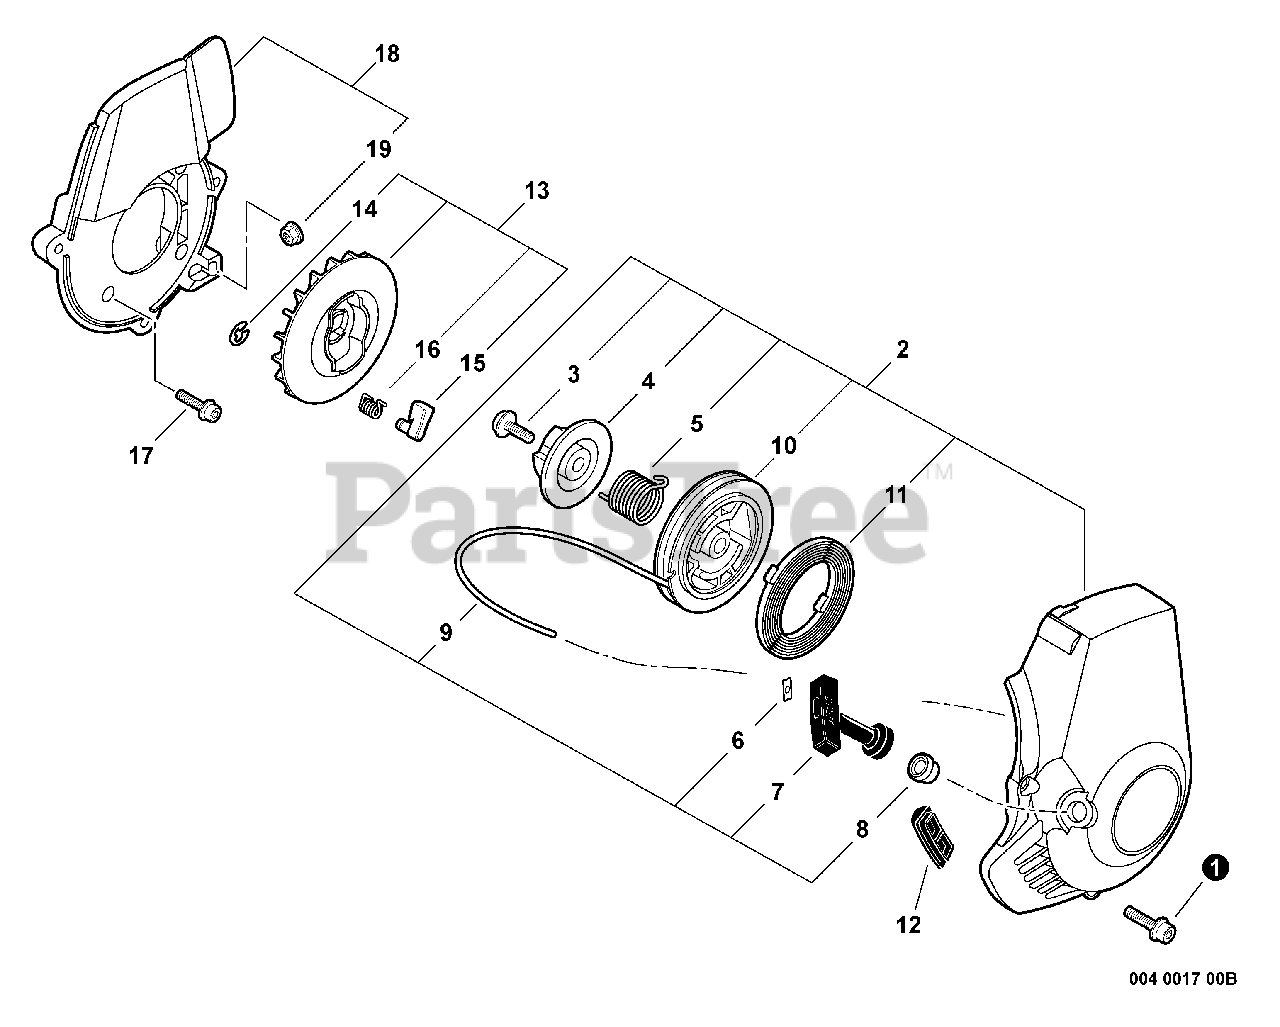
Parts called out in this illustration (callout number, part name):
1	SCREW - 5X14
2	STARTER ASSY
3	SCREW
4	PLATE, CAM
5	SPRING, DAMPER
6	RETAINER, ROPE
7	GRIP, STARTER
8	GUIDE, ROPE
9	ROPE, STARTER - 3X700
10	REEL, ROPE
11	SPRING, REWIND
12	CUSHION
13	STARTER PAWL ASSY
14	RING, RETAINING - 4
15	PAWL, STARTER
16	SPRING, RETURN
17	SCREW - 4X16
18	SPACER
19	NUT - 5 -- FLANGE
